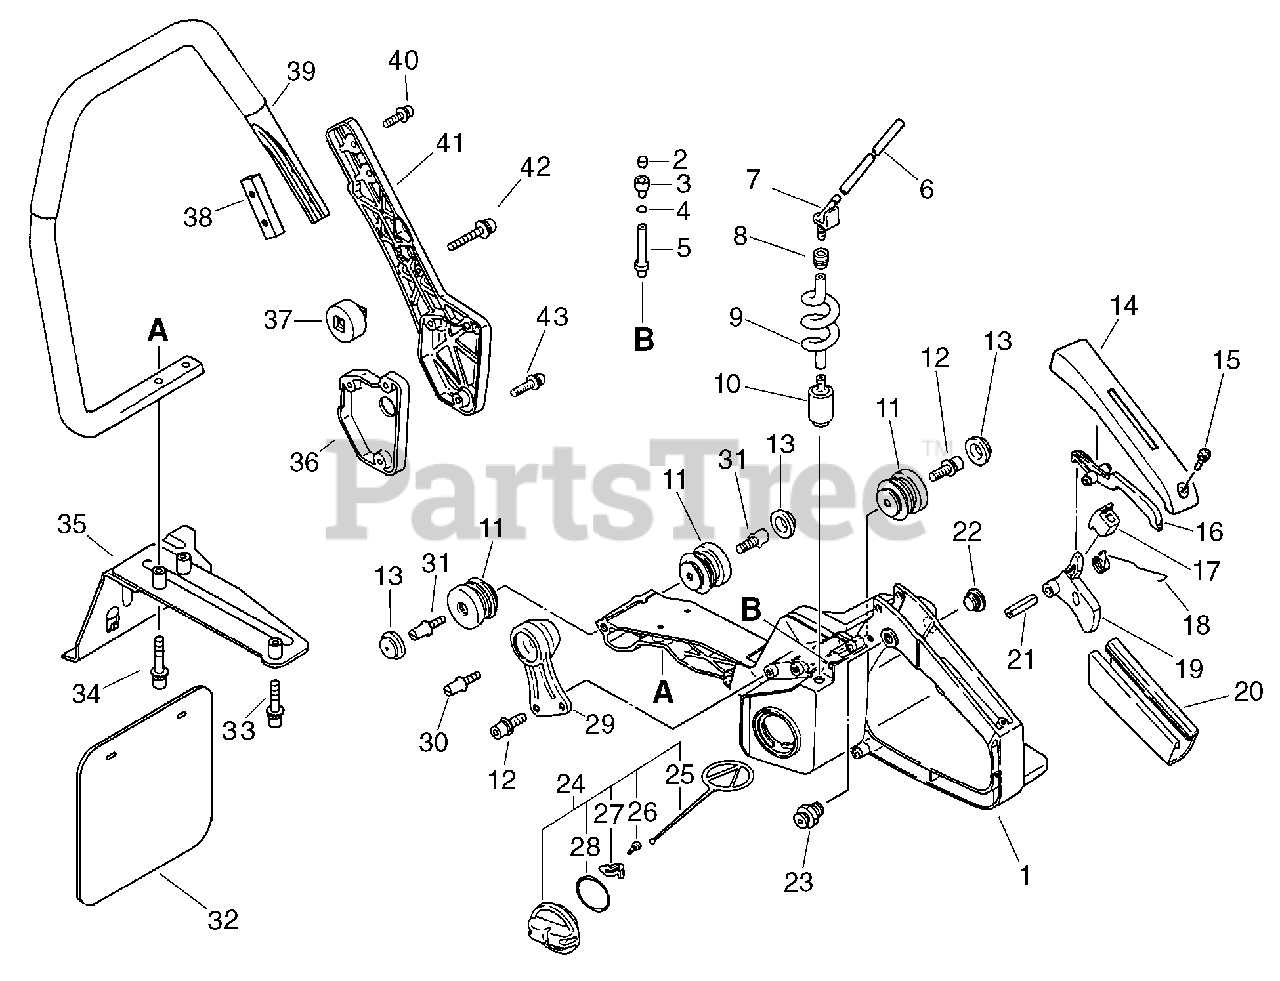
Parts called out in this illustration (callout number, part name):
1	HANDLE - REAR
2	VENT, FUEL TANK
3	COVER, VENT
4	CLIP - 5.5
5	PIPE - VENT
6	PIPE - 3X6X100 -- BLACK
7	CONNECTOR, PIPE
8	GROMMET
9	PIPE - BLACK
10	FILTER, FUEL
12	SCREW - 5X14
13	CAP, CUSHION
14	COVER, HANDLE
15	SCREW - 4X14
16	LOCKOUT, THROTTLE
17	CUSHION, THROTTLE
18	SPRING, TRIGGER
19	TRIGGER, THROTTLE
20	GRIP, HANDLE
21	PIN - SPRING -- 5X25
23	LATCH, THROTTLE
24	CAP ASSY
25	CONNECTOR, CAP
26	SCREW - 3X8
27	RETAINER
28	O-RING - 29
32	SHIELD
33	SCREW - 5X30
34	SCREW - 5X35
35	BRACKET, HANDLE
37	SPACER
39	HANDLE - FRONT
40	SCREW - 5X20
41	BRACKET, HANDLE
42	SCREW - 5X30
43	SCREW - 5X35
